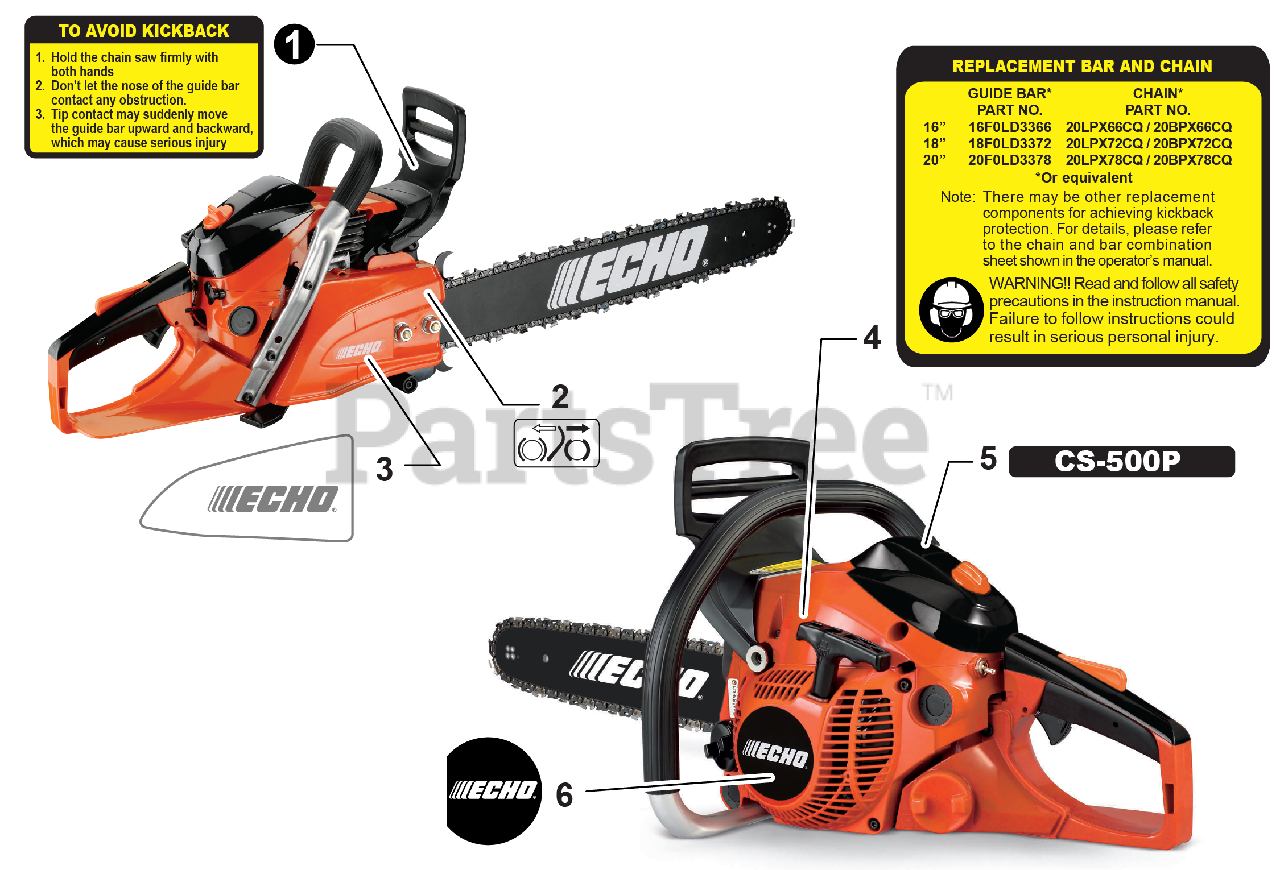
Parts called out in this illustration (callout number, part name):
1	LABEL, UL - KICK BACK
2	LABEL, CHAIN BRAKE
3	LABEL, ECHO
4	LABEL, BAR & CHAIN
5	LABEL, CS-500P
6	LABEL, ECHO
